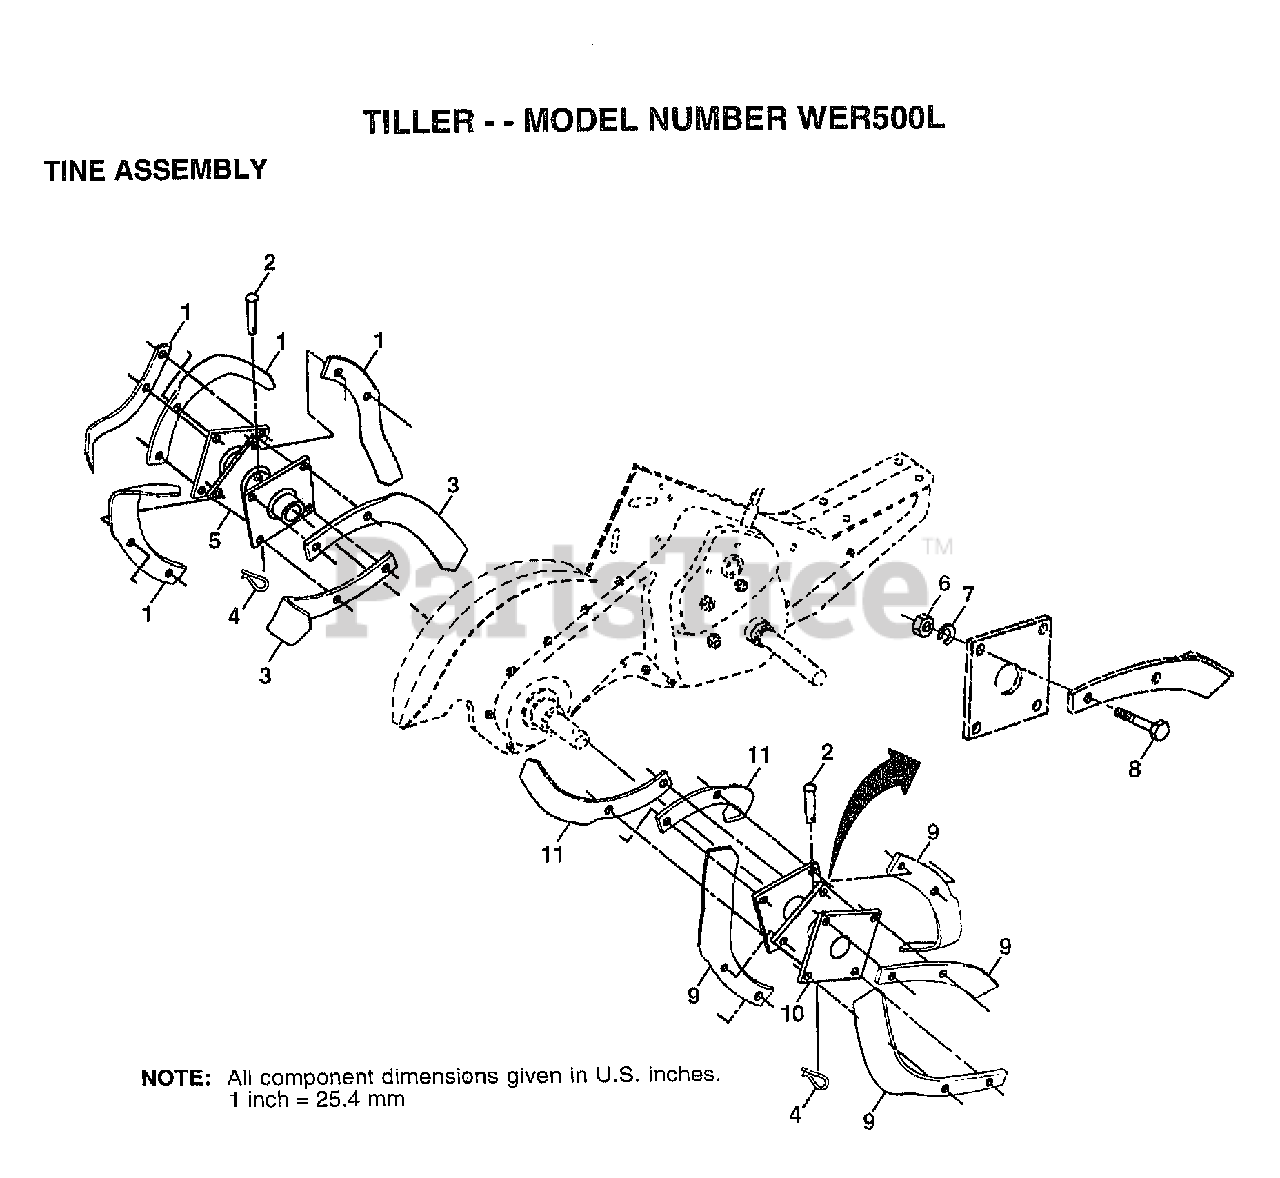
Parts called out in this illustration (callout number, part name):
2	PIN.CLEVIS.SHEAR
3	"TINE.LH.12"""
4	RETAINER SPRING
5	HUB&PLATE ASM LH
7	LOCKWASHER
8	BOLT
10	HUB&PLATE ASM RH
11	"TINE.RH.12"""
